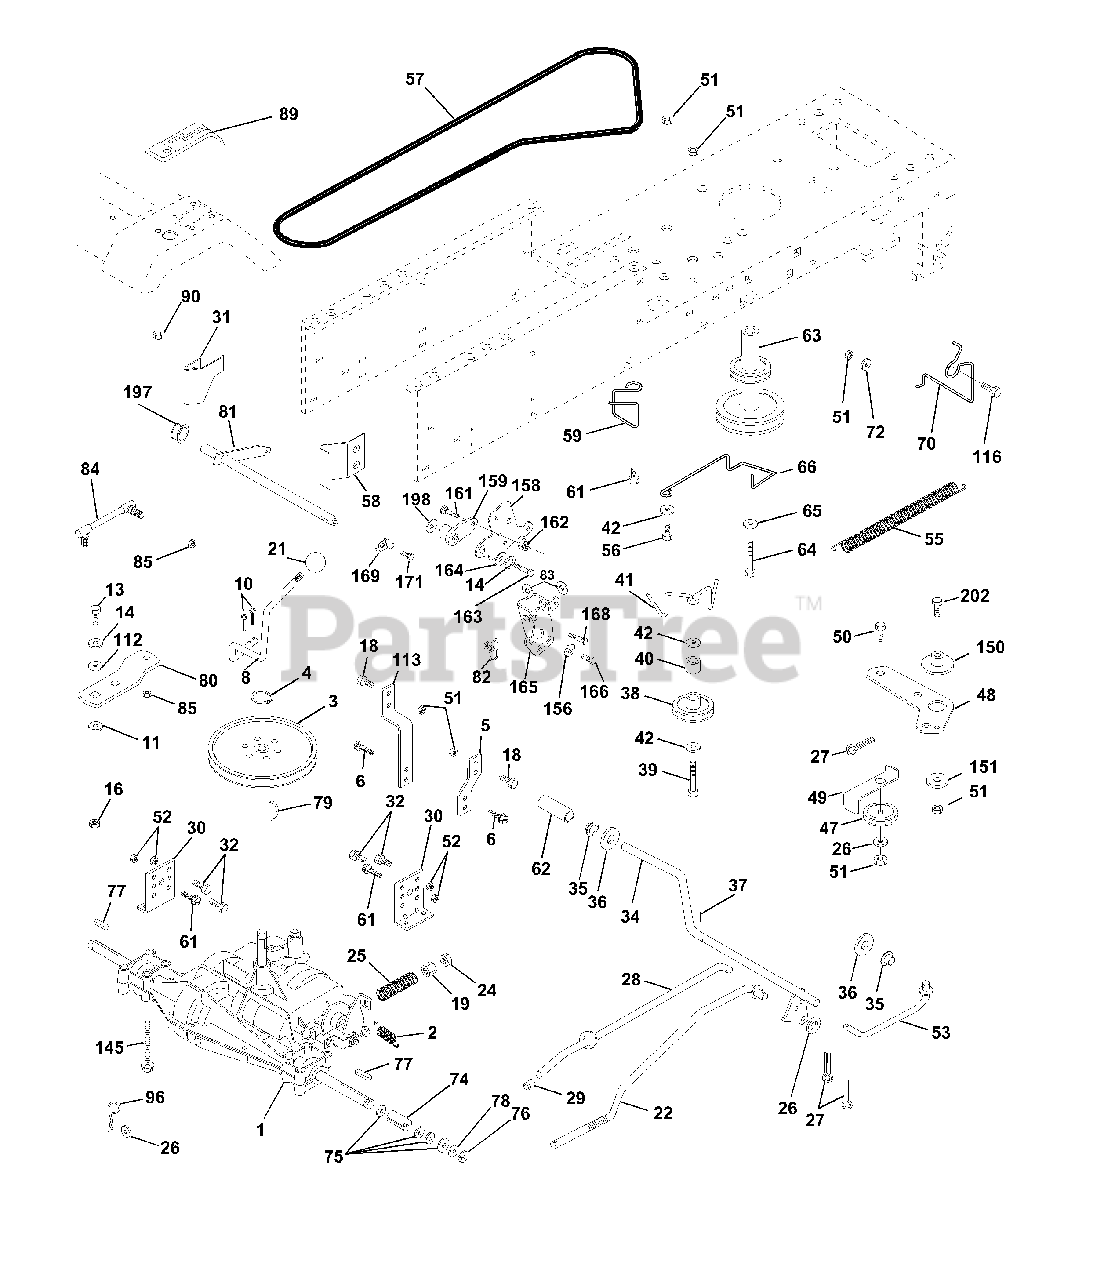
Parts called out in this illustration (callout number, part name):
1	Transaxle
2	Spring Return Brake T/a Zinc
3	Pulley Transaxle 18" tires
4	Ring Retainer #5100-62
5	Strap Torque 30 Degrees
6	Screw 5/16-18 x 3/4
8	Rod Shifter Fender Adj Lt
10	Pin Cotter 1/8 x 1 Cad
11	Washer Plate Shf 388 Sq Hole
13	Bolt 1/4-28 Unf Gr 8 W/Patch
14	Washer Lock Hvy Helical 1/4
16	Nut Lock
18	Bolt, Fin Hex 3/8-16 UNC x 1 Gr. 5
19	Nut Lock 3/8-16 Unc
21	Knob
22	Rod Brake Blk Zinc 26 840
24	Nut Hex Jam 3/8-16 Unc
25	Spring Rod Brake 2 00 Zinc
26	Washer 13/32 X 13/16 X 16 Ga
27	Pin Cotter 1/8 X 3/4 Cad
28	Rod Brake Parking LT/YT
29	Cap Brake Parking
30	Bracket Mtg Transaxle
31	Keeper Belt LH LT 14 Ga
32	Bolt Hex Hd 5/16-18unc X 3/4
34	Shaft Asm Pedal Foot
35	Bearing Nylon Blk 629 Id
36	Washer 21/32 X 1 X 16 Ga
37	Pin Roll 3/16 X 1"
38	Pulley Idler Flat
39	Bolt Fin Hex 3/8-16unc X 2-3/4
40	Spacer Split 395 X 59 Bzp
41	Keeper Belt Retainer Idler
42	Washer 13/32 X 13/16 X 12 Ga
47	Pulley Idler V Groove Plastic
48	Bellcrank Asm
49	Retainer Belt Style Spring
50	Bolt Hex Hd 3/8-16unc X 1-1/2
51	Nut Crownlock 3/8-16 Unc
52	Nut Crownlock 5/16-18 Unc
53	Link Clutch
55	Spring Return Clutch 6 75
56	Bolt Fin Hx 3/8-16 X 1-1/4
57	V-Belt Ground Drive
58	Keeper Belt RH LT Pnt/zinc 16g
59	Keeper Belt Span Ctr
61	Screw 3/8-16 x 3/4
62	Cover Pedal Blk Round
63	Engine Pulley LT/YT
64	Bolt Hex
65	Washer Lock Hvy Hlcl Spr 7/16
66	Keeper Belt Engine Foolproof
70	Guide Belt Mower Drive RH
72	Washer 13/32 X 1-1/4 X 12 Ga
74	Spacer Axle
75	Washer 25/32 X 1 1/4 X 16 Ga
76	E-ring #5133-75
77	Key Square 2 0 X 1845/ 1865
78	Washer 25/32 X 1-5/8 X 16 Ga
79	Key Woodruff
80	Arm Shift
81	Shaft Asm Cross Tapered 20"t
82	Spring Torsion T/a
83	Washer 17/32 X 3/4 X 16 Ga
84	Link Transaxle
85	Nut Lock Center 1/4 - 28 FNTHD
90	Nut Self-thd Wsh-hd 1/4 Zinc
96	Retainer Spring
112	Washer
113	Strap Torque Lh
116	Bolt Rdhd Sq Neck 3/8-16 x 1.25
145	Bolt Hex 5/16-18 Gr. 5
150	Bushing Bellcrank Grd. Drive
151	Washer 13/32 x 2 x 10
156	Washer Srrted 5/16 ID x 1.125
158	Bracket Shift Mount
159	Hub Tapered Flange Shift lt
161	Bolt Rdhd Sqnk 1/4-20 x 3/4 Gr 5
162	Nut Crownlock 1/4-20 Unc
163	Bolt Hex Fin 1/4-20 Unc x 1 Gr 5
164	Washer 5/8 x .281 x 10 Ga
165	Bracket Pivot Lever
166	Screw 5/16-18 x 5/8
168	Bolt Shoulder 5/16-18 x .561
169	Plate Fastening Lt
171	Screw Thdrol 3/8-16 x 1/2
197	Nyliner, Snap - in
198	Washer, Nyl.
202	Bolt, Carriage 3/8 - 16 x 1
